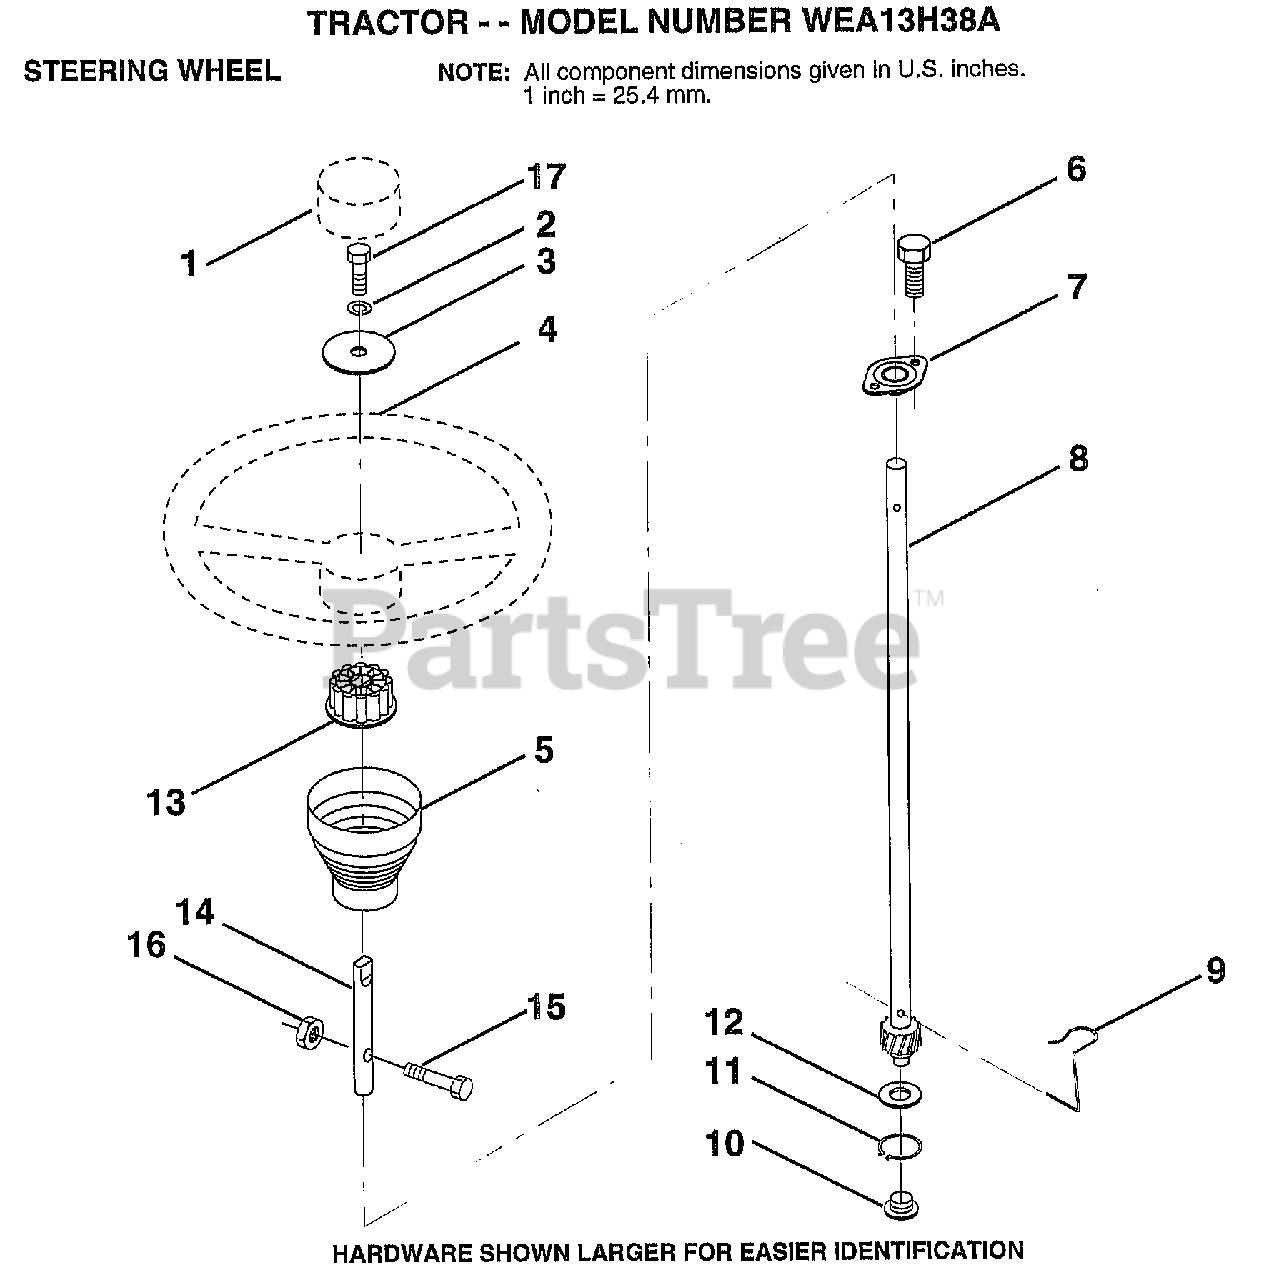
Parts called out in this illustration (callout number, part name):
1	ST WHL INSERT CAP
2	LOCKWASHER
3	WASHER T
5	SLEEVE STEERING
6	"SCREW-TT,10-32 FL"
7	BUSHING.STR.623
8	SHAFT.STEERING.LR
9	STEERING CLIP
10	BUSHING STEER LWR
11	RING
12	WASHER LT
13	ADAPTER LT
14	EXT SHAFT STEERIN
15	BOLT
16	NUT
17	BOLT
